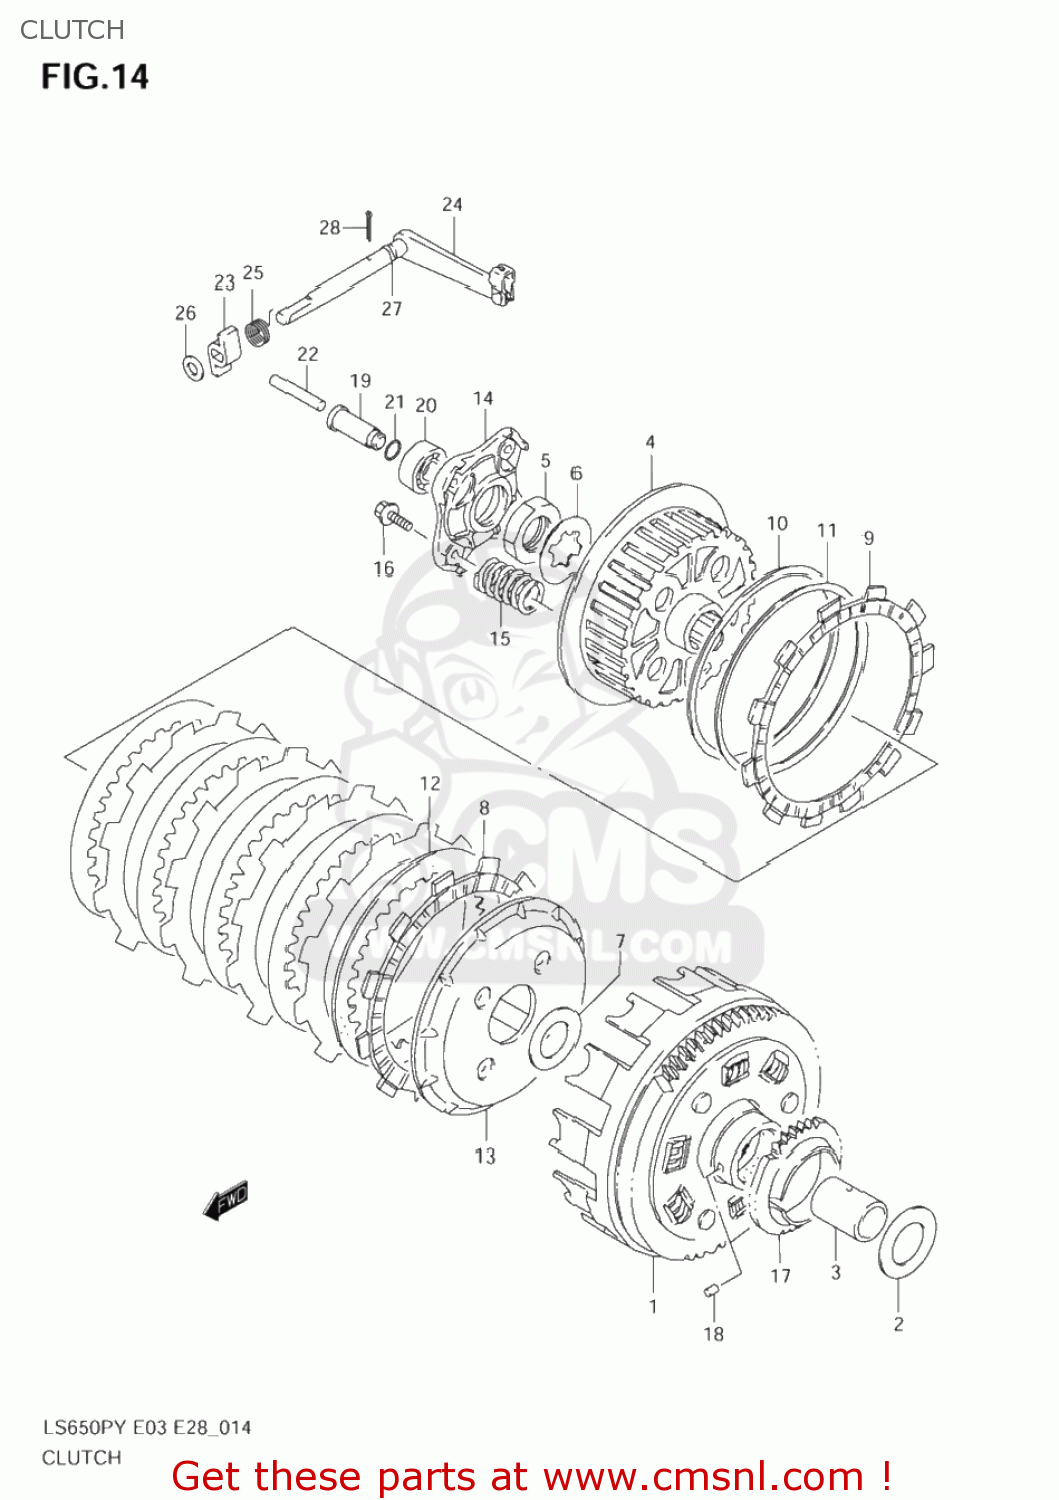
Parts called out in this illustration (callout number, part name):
1	GEAR ASSY,PRI DRIVEN
2	WASHER
3	SPACER(22X28X32.5)
4	HUB,CLUTCH SLEEVE
5	NUT
6	WASHER,LOCK
7	WASHER
8	PLATE,CLUTCH DRIVE (NAS)
9	PLATE,CLUTCH DRIVE(T:3.5) (NAS)
10	SEAT,WAVE WASHER(T:1.4)
11	WASHER
12	PLATE,CLUTCH DRIVEN(T:1.6) (NAS)
13	DISC,CLUTCH PRESSURE
14	PLATE,RELEASE
15	SPRING
16	BOLT
17	GEAR,ENG OIL PUMP DRIVE
18	PIN(6X6)
19	PIECE,CLUTCH PUSH
20	BEARING(12X28X8)
21	O RING(D:1.9,ID:8.6)
22	ROD,CLUTCH PUSH
23	CAM,CLUTCH RELEASE
24	ARM ASSY,CLUTCH RELEASE
25	SPRING
26	WASHER,THRUST
27	O RING(D:1.9,ID:6.8)
28	PIN 20X20
